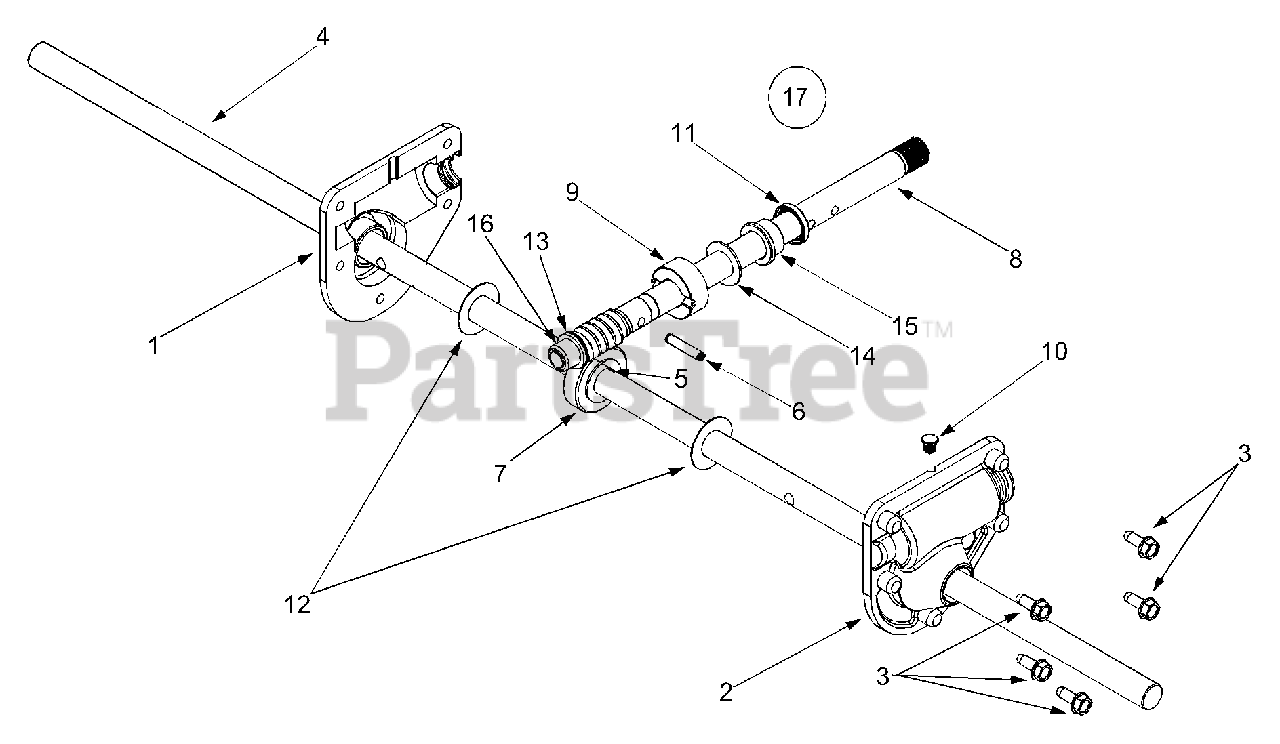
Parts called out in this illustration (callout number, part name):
1	RH Reducer Housing
2	LH Reducer Housing
3	Hex Screw 1/4-20 x.75
4	Spiral Axle 24"
5	Key
6	Pin-Spiral
7	Worm Gear, 20T
8	Worm Shaft
9	Thrust Collar
10	Grease Plug
11	Grease Seal
12	Flat Washer.76 x 1.5 x.030
13	Flat Washer.508 x 1.0 x.020
14	Flat Washer.76 x 1.5 x.060
15	Flange Bearing.75 x 1.0 x.59
16	Flange Bearing.75 x 1.0 x.925
17	Gearbox Ass'y. Complete 24"
